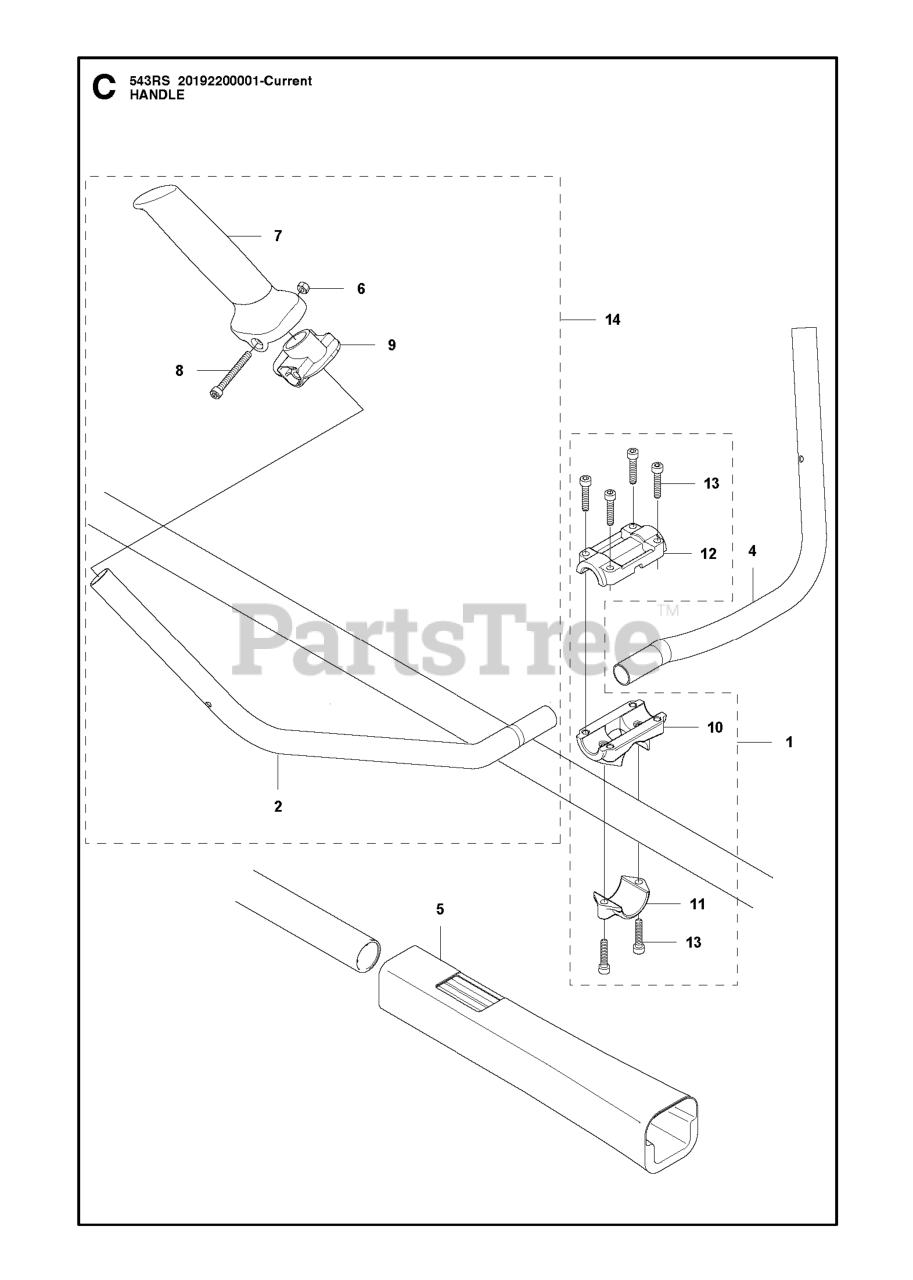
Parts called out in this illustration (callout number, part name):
1	HANDLE BRACKET ASSY 243R
5	PROTECTOR (RPLS 405017110)
6	NUT
10	BRACKET Z354314112
11	CAP-L Z354314121
14	HANDLE(L)-A
